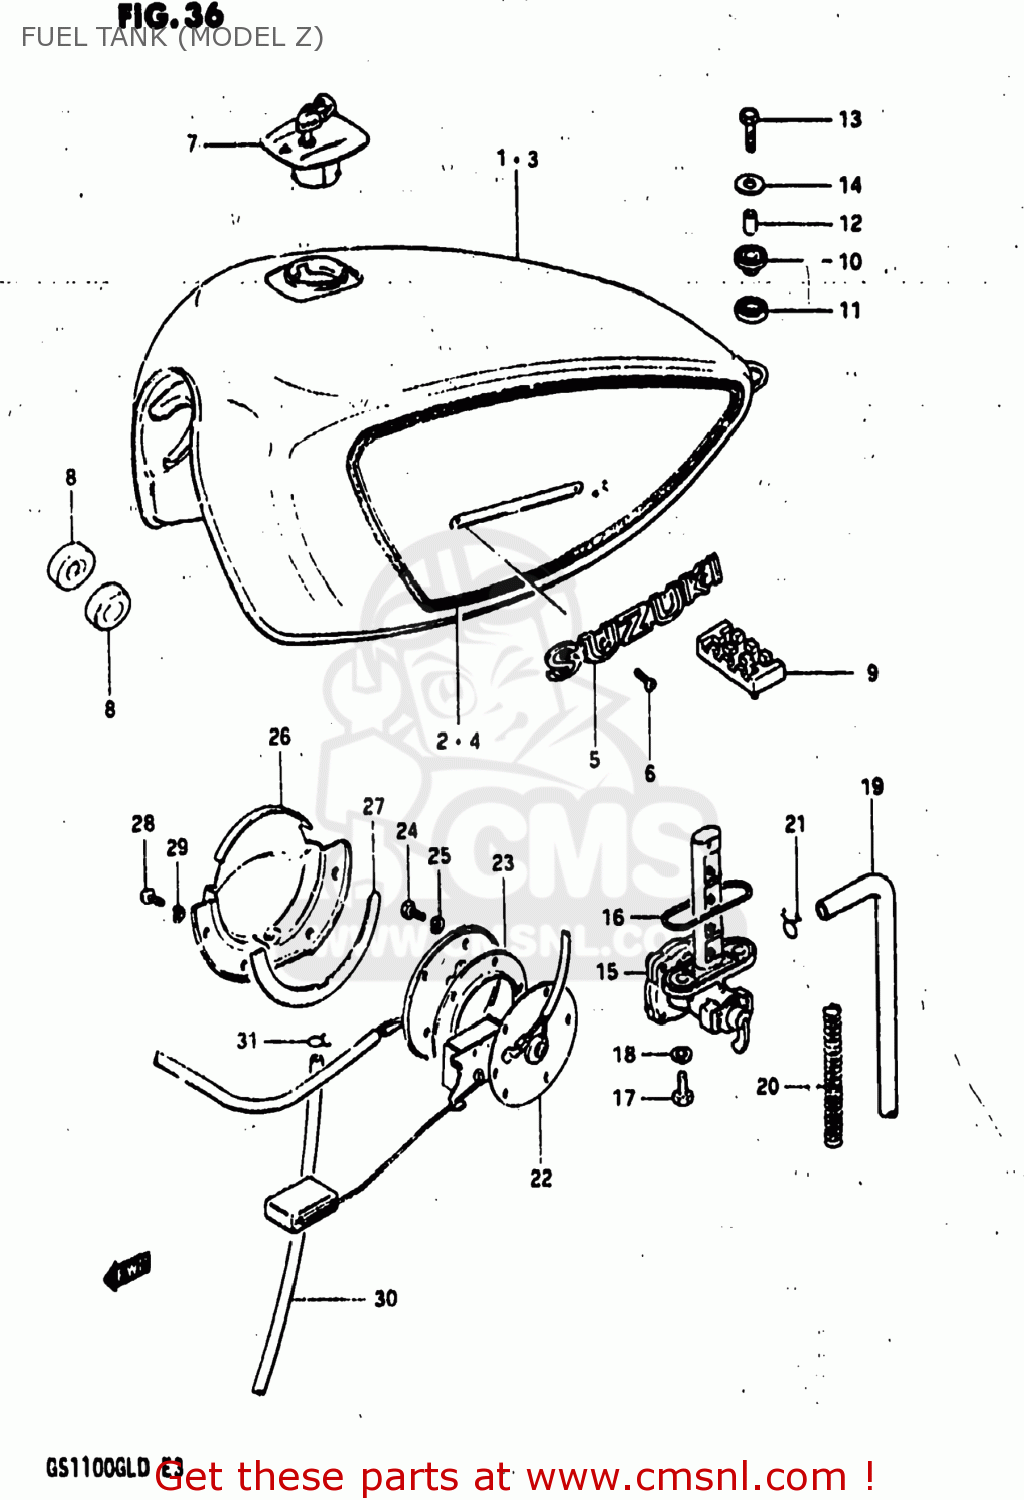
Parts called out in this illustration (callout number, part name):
1	TANK ASSEMBLY,FUEL
2	TAPE SET,FUEL TANK
3	TANK ASSEMBLY,FUEL
4	TAPE SET,FUEL TANK
5	EMBLEM,FUEL TANK
6	SCREW 3X6
7	CAP SET,FUEL TANK
8	CUSHION
9	CUSHION,FUEL TANK CTR
10	CUSHION
11	CUSHION
12	SPACER
13	BOLT
14	WASHER (6.5X24X1.6)
15	COCK ASSEMBLY,FUEL
16	O RING
17	BOLT(6X20)
18	GASKET
19	HOSE
20	SPRING
21	CLIP
22	GAUGE ASSEMBLY,FUEL LEVEL
23	GASKET,FUEL LEVEL GAUGE (NAS)
24	BOLT
25	LOCK WASHER
26	PLATE,FUEL DRAIN
27	GASKET (NAS)
28	SCREW
29	LOCK WASHER
30	HOSE
31	CLIP
